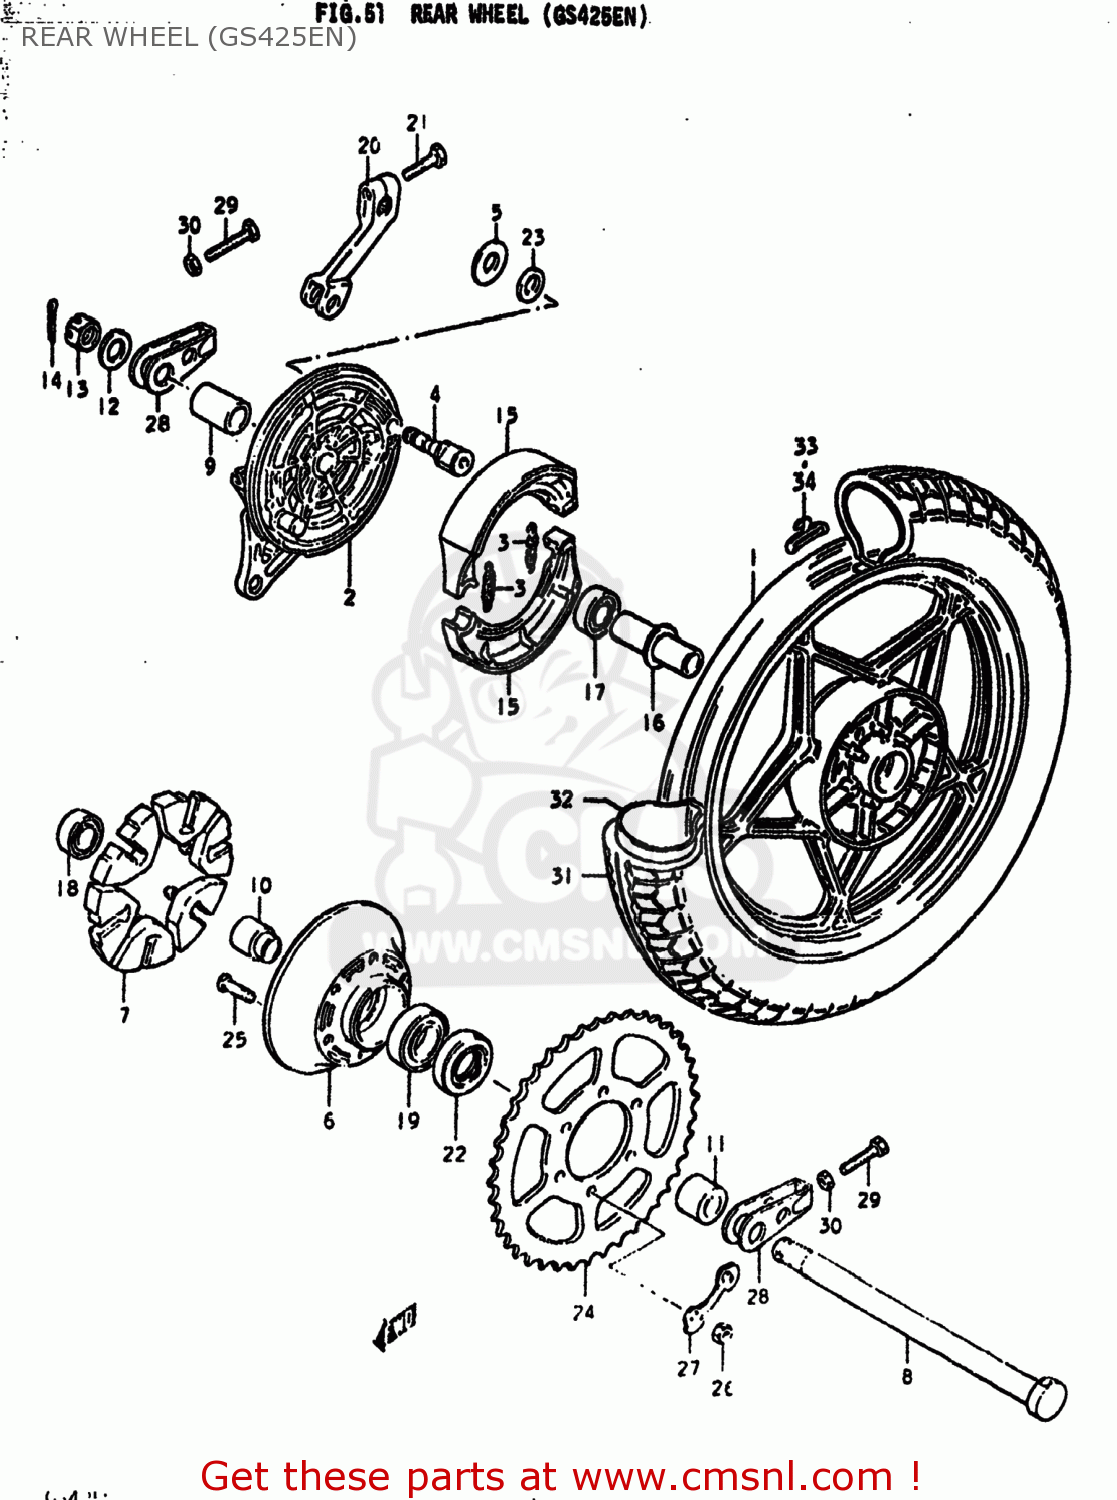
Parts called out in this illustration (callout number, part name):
1	WHEEL,REAR
2	PANEL,REAR HUB
3	SPRING,BRAKE SHOE
4	CAM,FRONT BRAKE
5	WASHER (15X24X1.6)
6	DRUM,REAR SPROCKET MOUNT
7	ABSORBER,RR HUB SHOCK
8	AXLE,REAR
9	SPACER(17.5X28X44.8)
10	SPACER,REAR HUB BEARING
11	SPACER(17X30.5X22.3)
12	WASHER (17X30X3.2)
13	NUT
14	PIN,COTTER
15	SHOE SET,BRAKE
16	SPACER
17	BEARING
18	BEARING
19	BEARING
20	LEVER,REAR BRAKE CAM
21	BOLT
22	OIL SEAL
23	O-RING,BOSS
24	SPROCKET,RR
25	BOLT
26	NUT
27	WASHER
28	ADJUSTER,CHAIN
29	BOLT
30	NUT
31	TIRE
32	TUBE ASSEMBLY,WHEEL,INNER
33	BALANCER,WHEEL
34	BALANCER,WHEEL
